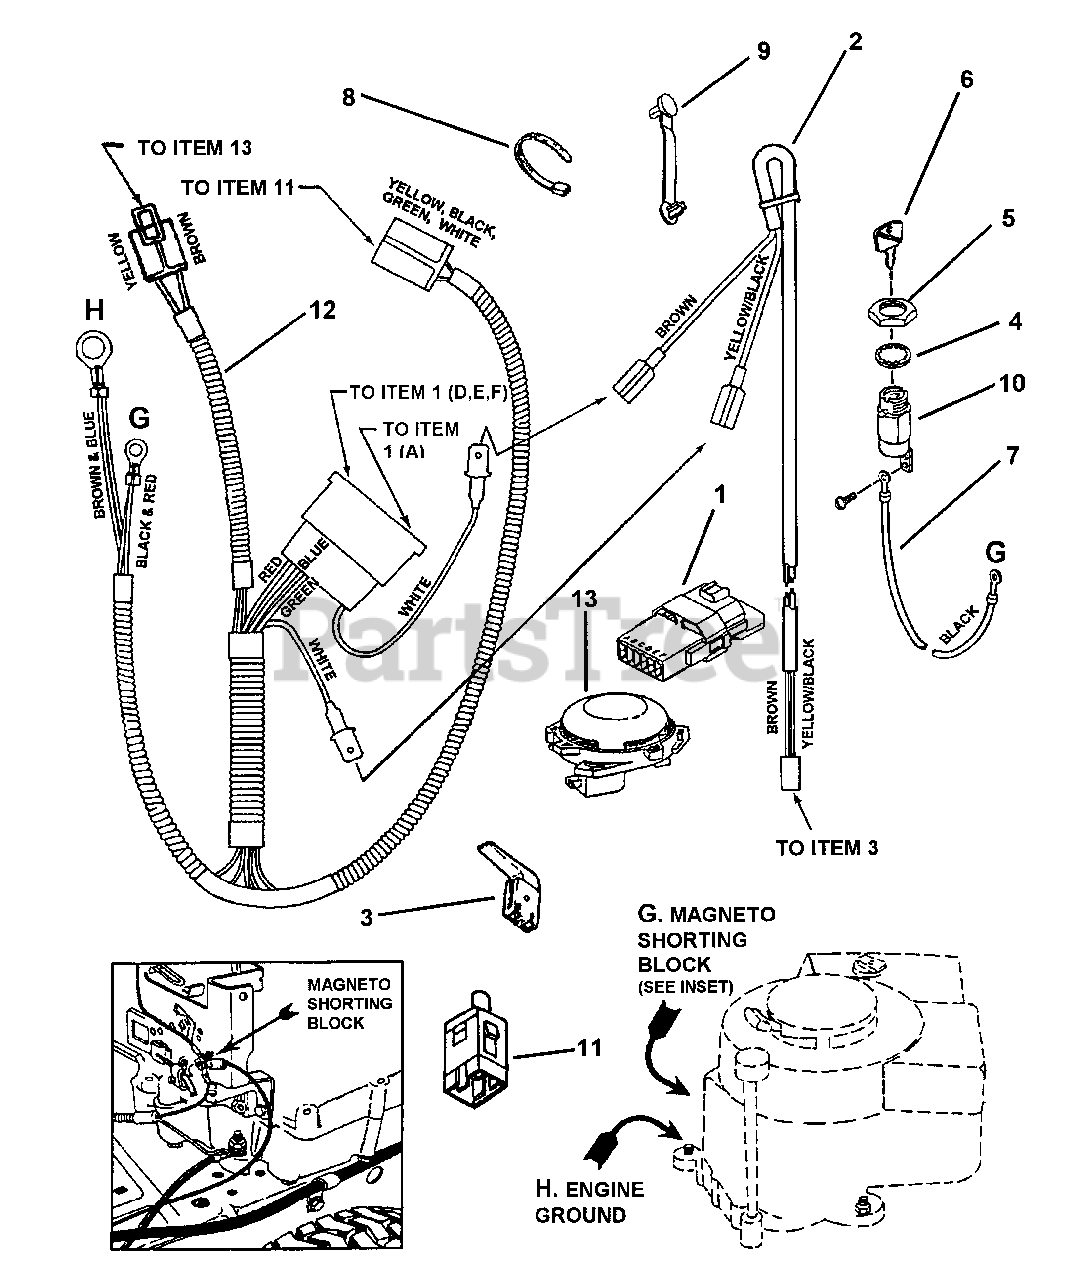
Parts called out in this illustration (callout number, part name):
1	INTERLOCK, Module (Briggs)
2	HARNESS, Deck Interlock
3	SWITCH, Deck Interlock Wiring (NO)
4	WASHER, 5/8 Internal Tooth Lock
5	NUT, 5/8-32 Hex
6	KEY, Switch
7	WIRE, Ground (Recoil Start)
8	TIE, 7" Long Cable
9	TIE, 2" Long Cable
10	SWITCH, (Recoil Start) (NC in off position)
11	SWITCH, Operator's Presence (OPC) Traction (NC/NO)
12	HARNESS, Operator's Presence Control (OPC) Wire
13	SWITCH, Seat (8 HP & 10 HP Engines) (NC)
